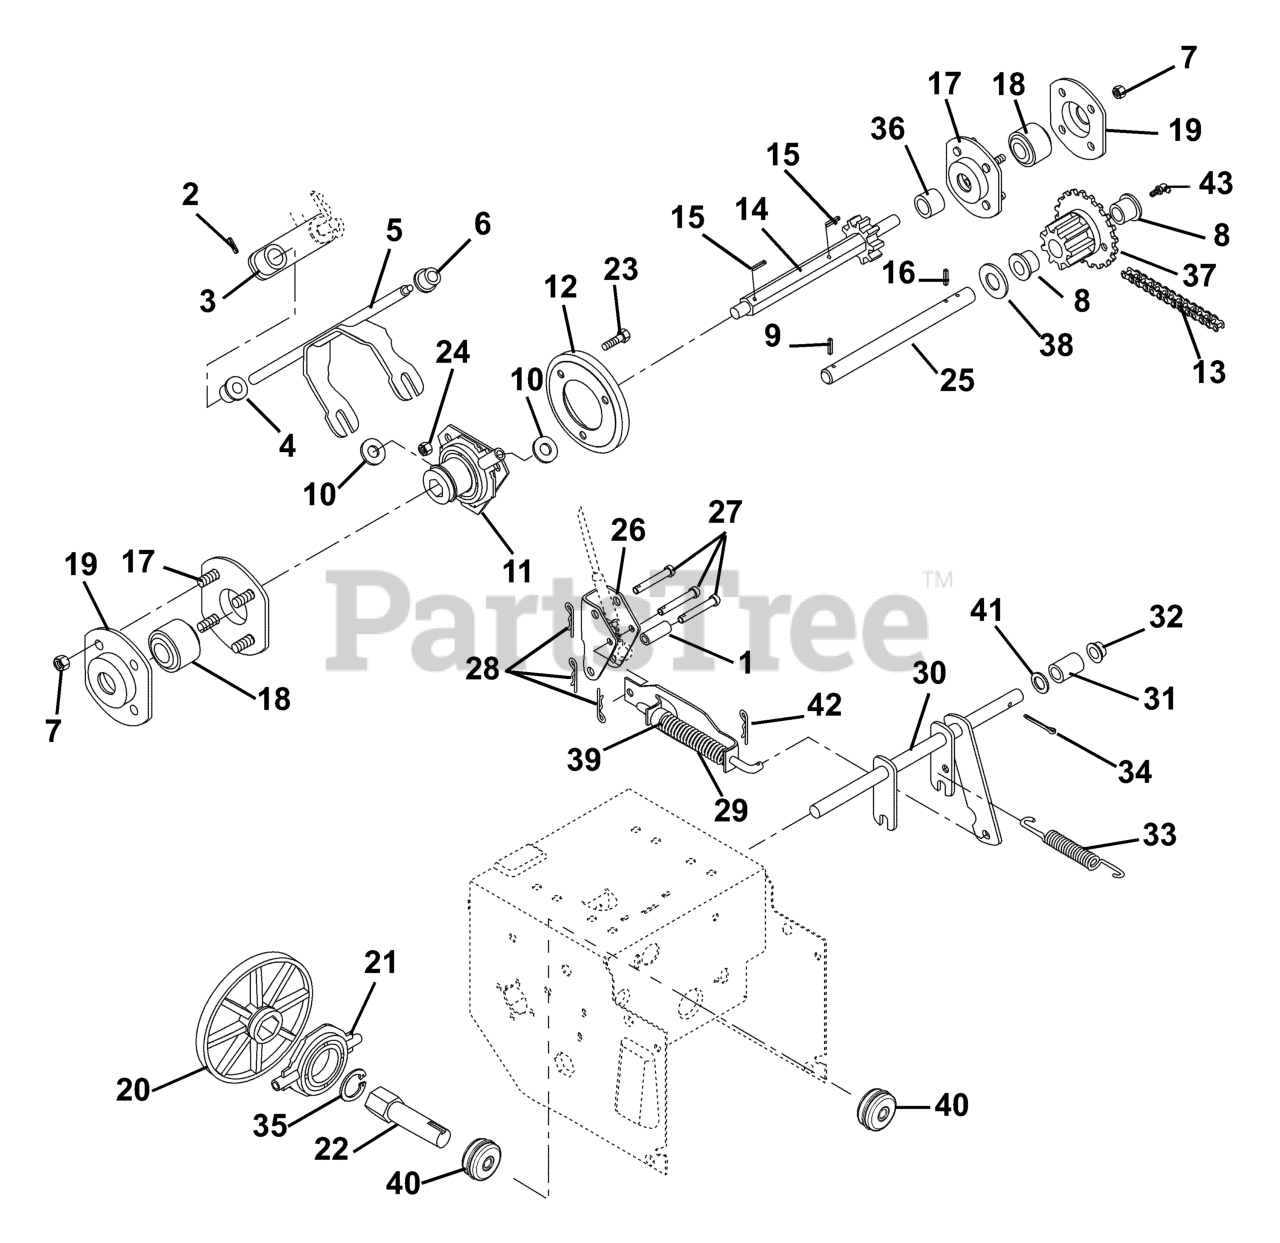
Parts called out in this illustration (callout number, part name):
1	SPACER .325 X.625 X.455
2	PIN-ROLL .156X.88
3	WMT,SPEED CHANGE ARM
4	BSHG-FLG .500X.625X.500X.750
5	FORK-SPEED
6	BSHG-FLG .325X.444X.440X.560
7	NUT-LK-DUAL FACE 10-24 YWZC
8	BSHG-FLG .625X.750X.500X.875
9	PIN-ROLL .156X1.00
10	WSHR-FL-STL .505X1.00X.062YWZC
11	SHIFT CARRIER
12	DISC, FRICTION - 730 MAT'L
13	CHAIN, ROLLER #41 X 27 P
14	WMT, HEX SHAFT
15	PIN-ROLL .125X.88
16	PIN-ROLL .125X1.00
17	BEARING FLANGE
18	BRG-BALL .437X1.375X.437
19	BEARING FLANGE
20	FRICTION PLATE
21	BEARING ASSEMBLY
22	SPINDLE SHAFT, 932 DRIVE PLATE
23	@BLT-HEX .25-20X.50 GR5 YWZC
24	@NUT-LK-CTR .25-20 YWZC
25	SHAFT-PINION
25	SHAFT, PINION
26	BRACKET, TRACTION ARM
27	PIN,CLEVIS .243/.248 X 1.38 YZ
28	PIN-HAIR INT .06X.18X.77
29	TRACTION CLUTCH ASSEMBLY
30	CLUTCH FORK
31	SPACER .504X.748X.321
32	CAP, .50 ROD YWZC
33	SG-TENS .063X.44X1.56
34	@PIN-CTR .12X1.00 EXTPRSQCT YZ
35	RG-RTNG-EXT 1.250X.050
36	SPACER,.45 X .62 X 1.23
37	ASSY,PINION & SPROCKET
38	WSHR-FL-STL .630X1.005X.062 YZ
39	SPACER .325 X.625 X.455
40	BRG-BALL,.625X1.38X.43 SNAP RG
41	@WSHR-FL-STL.531X1.06X.095YWZC
42	PIN-HAIR INT .08X.18X1.18 YWZC
43	DRIVE FITTING, HYD. BRIGHT ZC
